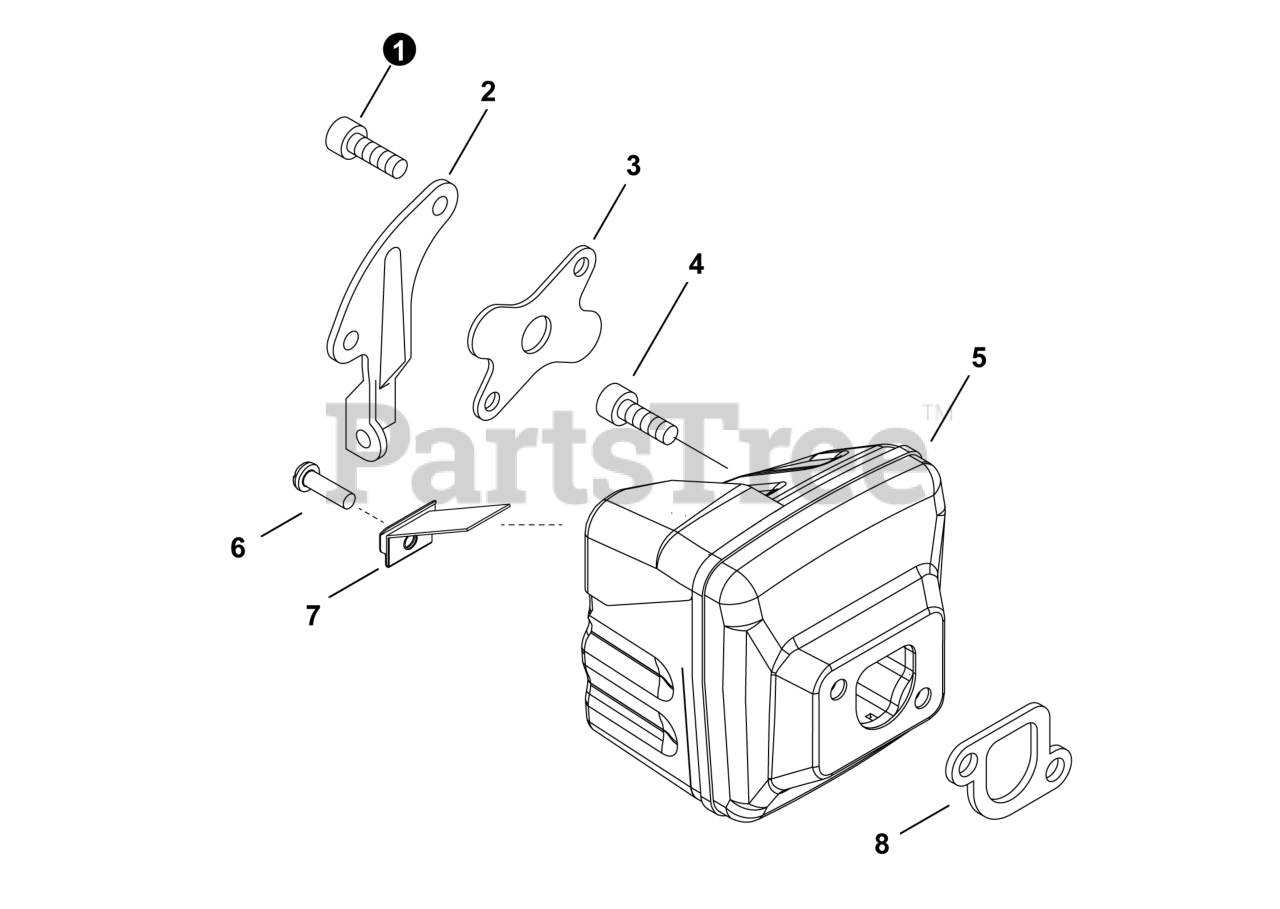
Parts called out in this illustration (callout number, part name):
1	BOLT 5×10
2	BRACKET, MUFFLER
3	COVER, MUFFLER
4	BOLT 6×20
5	MUFFLER
6	SCREW 4×8
7	SCREEN, SPARK ARRESTER
8	GASKET, MUFFLER
